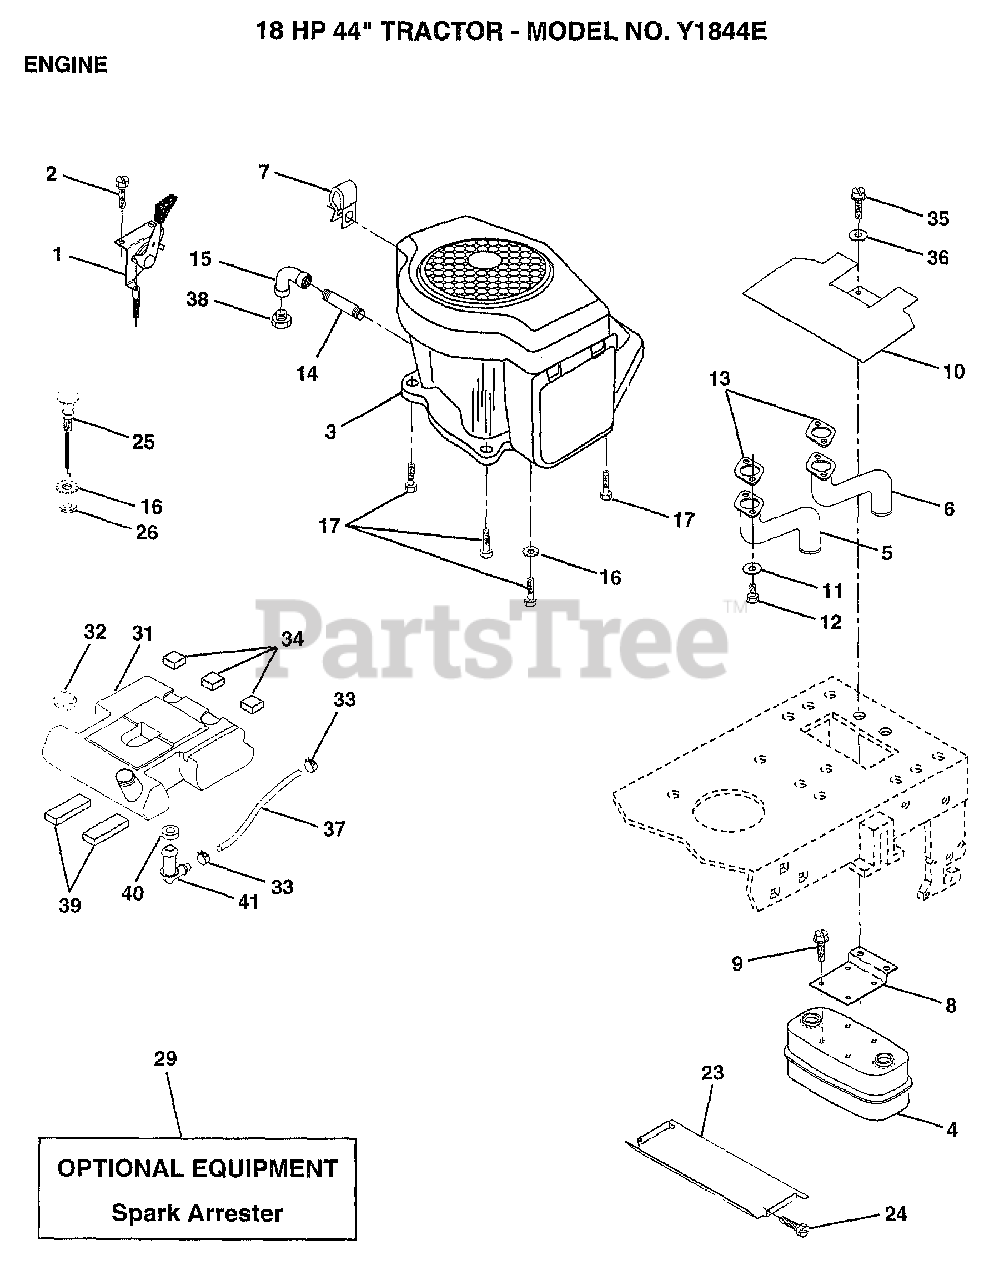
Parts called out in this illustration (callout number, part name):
1	CONTROL.THROTTL
2	SCREW LT
5	"TUBE,MANIFOLD LH"
6	"TUBE,MANIFOLD RH"
7	CLIP T
8	BRACKET MUFFLER
9	SCREW ST
10	SHIELD HEAT LT
11	LOCKWASHER
12	SCREW
14	PIPE NIPPLE LT
15	ELBOW
16	LOCKWASHER
17	SCREW LT
23	HEAT SHIELD
24	SCREW
32	CAP ASM FUEL
33	HOSE CLAMP
34	PAD-SPACER LT
35	SCREW
36	WASHER
37	FUEL LINE T
39	PAD IDLER TI
40	BUSHING OUTLET T
41	STEM.TANK.FUEL
